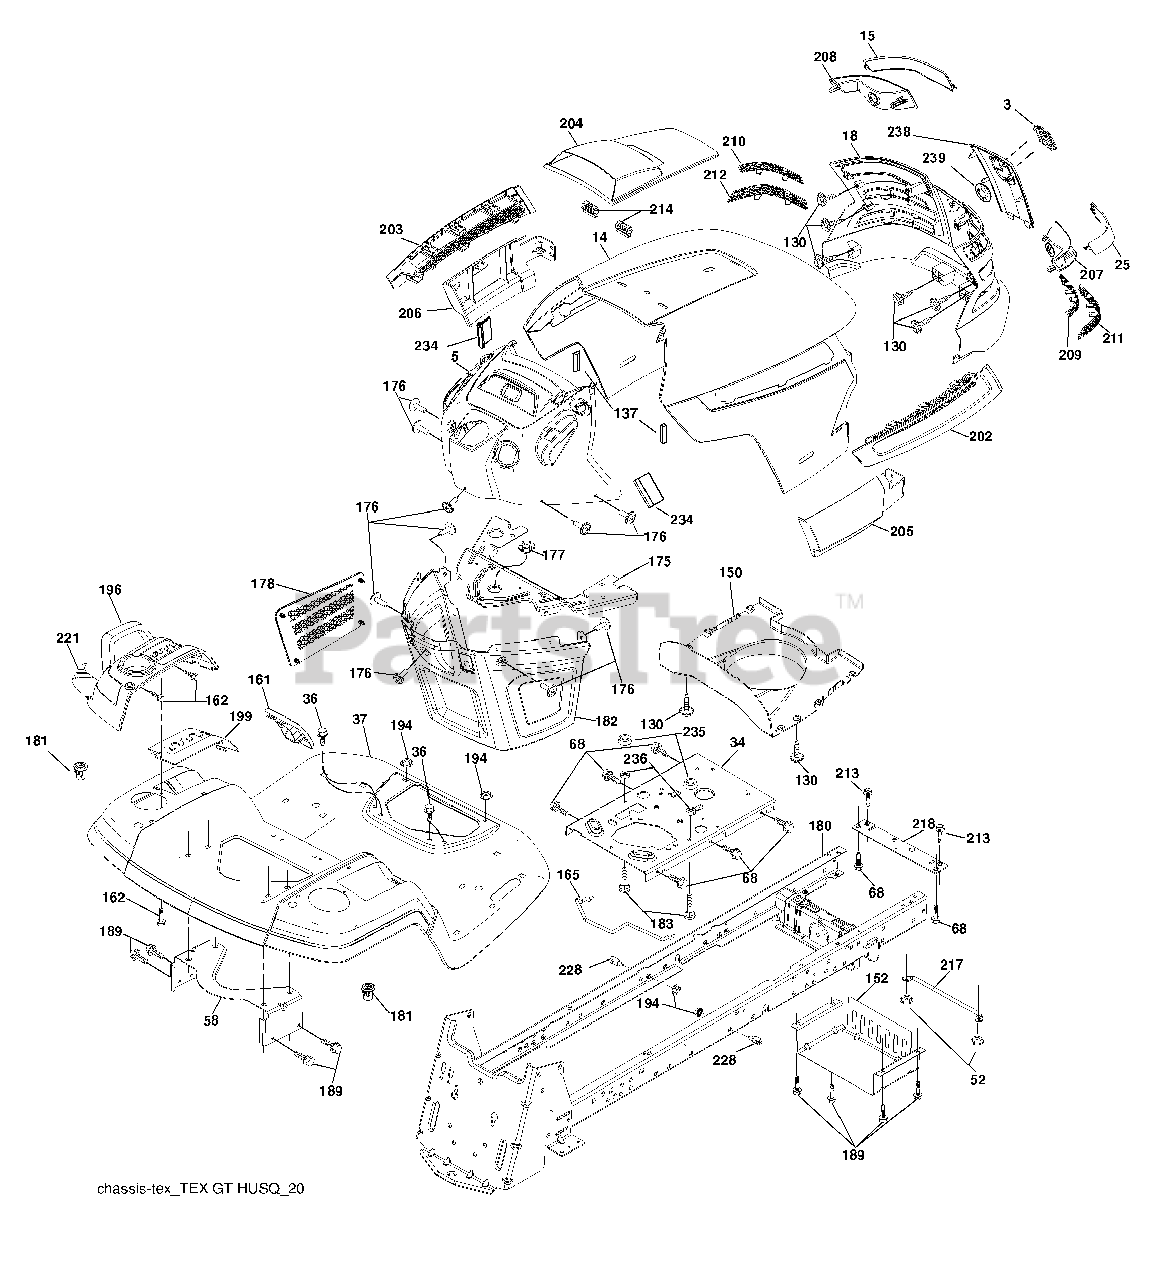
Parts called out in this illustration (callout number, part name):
3	Logo Husq
14	Hood
34	Plate Engine
36	Screw 5/16-18 x 3/4
37	Fender
52	Nut Lock 5/16-18
58	Bracket Fender
68	Screw 5/16-18 x 1/2
130	Screw #10 x 0.750
137	Bumper Dash
150	Duct Heat Hood
152	Shield Browning/Debris
161	Console Fuel Window
162	Screw Hex Wsh Hi-Lo 1/4 x 1/2
165	Bracket Support Tank
175	Crossmember
176	Screw 10-24 x 5/8 Rnd Qdrx
177	Bushing Steering
178	Cargo Asm. Net
180	Chassis
181	Bushing Mtg. Fender Crgo.
182	Dash Lower
183	Bolt 5/16-18 x 1-1/4
189	Screw 5/16-18 x 3/4
194	Nut Lock Hex Flange 5/16-18
196	Console Asm. Deck Lift
199	Plate Deck Lift
202	Vent Side Hood RH
203	Vent Side Hood LH
204	Vent Asm Hood Top
205	Skirt Hood Side RH
206	Skirt Hood Side LH
209	Insert Hex Top RH
210	Insert Hex Top LH
211	Insert Hex Bottom RH
212	Insert Hex Bottom LH
213	Bolt Hex Hd 5/16-18 unc x 3/4
214	Clip Retainer
217	Rod Pivot Hood
221	Reflector LH
228	Stud Fastner
234	Bumper Hood
235	Spacer Fender
236	Nut Lock 5/16-18 unc
239	Plug Mount
